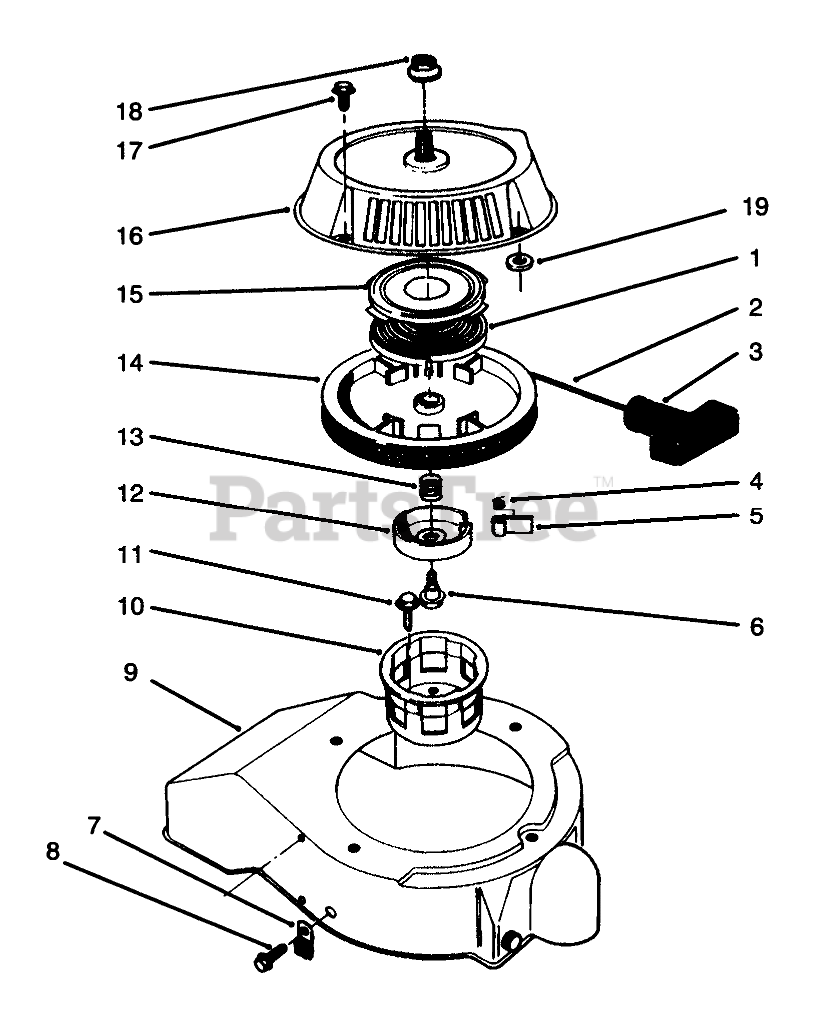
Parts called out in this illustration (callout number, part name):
1	SPRING
2	ROPE-STARTER
3	HANDLE-RECOIL
4	SPRING
7	CLAMP
9	SHROUD
10	CUP - STARTER
12	RETAINER
13	SPRING
15	Retainer-Recoil Spring
16	RECOIL CASE
17	MOUNTING SCREW
18	NUT (F/W & PPP)
19	SPACER-PLATE, PIVOT
